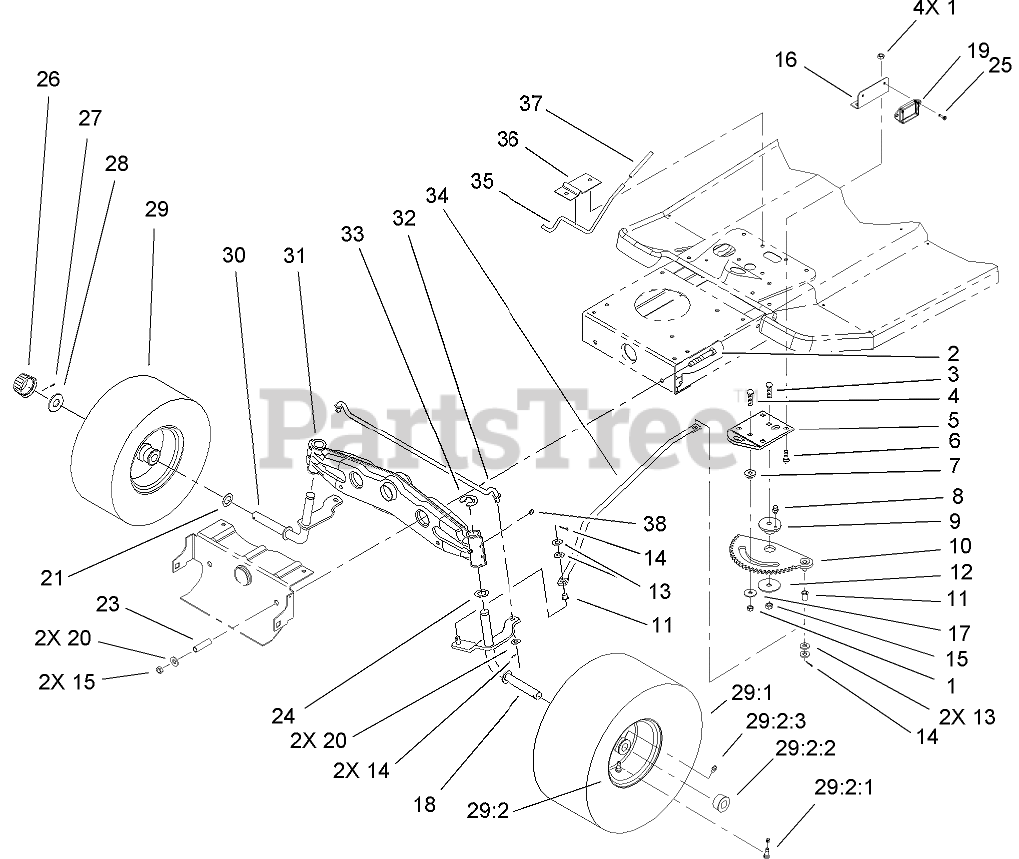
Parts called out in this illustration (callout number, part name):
1	NUT-LOCK, NI
2	SCREW-HH
3	SCREW-CARR
4	SCREW-CARR
5	BRACKET-RACK, STEERING
6	BOLT-CARR
7	SPACER-RACK, STEERING
8	FITTING-GREASE
9	BUSHING-ECCENTRIC
10	RACK-STEERING
11	BUSHING-FLANGED, NYLON
12	WASHER-BEARING
13	WASHER-FLAT
14	PIN-COTTER
15	NUT-LOCK, NI
16	BRACKET-MODULE
17	WASHER-PIVOT
18	LH SPINDLE ASM
19	MODULE
20	WASHER-FLAT
21	WASHER-THRUST
23	SPACER
24	WASHER-THRUST
25	SCREW-HWH
26	CAP-HUB
27	PIN-COTTER
28	WASHER-PLAIN
29	FRONT WHEEL and TIRE ASM
29:2	RIM ASM
29:2:1	STEM-VALVE
29:2:2	BEARING-WHEEL
29:2:3	FITTING-GREASE
30	RH SPINDLE ASM
31	AXLE-FRONT
32	TIE ROD-STEERING
33	E-RING
34	LINK-DRAG
35	ROD-BRAKE, PARKING
36	BRACKET-PARKING BRAKE
37	GRIP-BRAKE, PARKING
38	FITTING-GREASE
